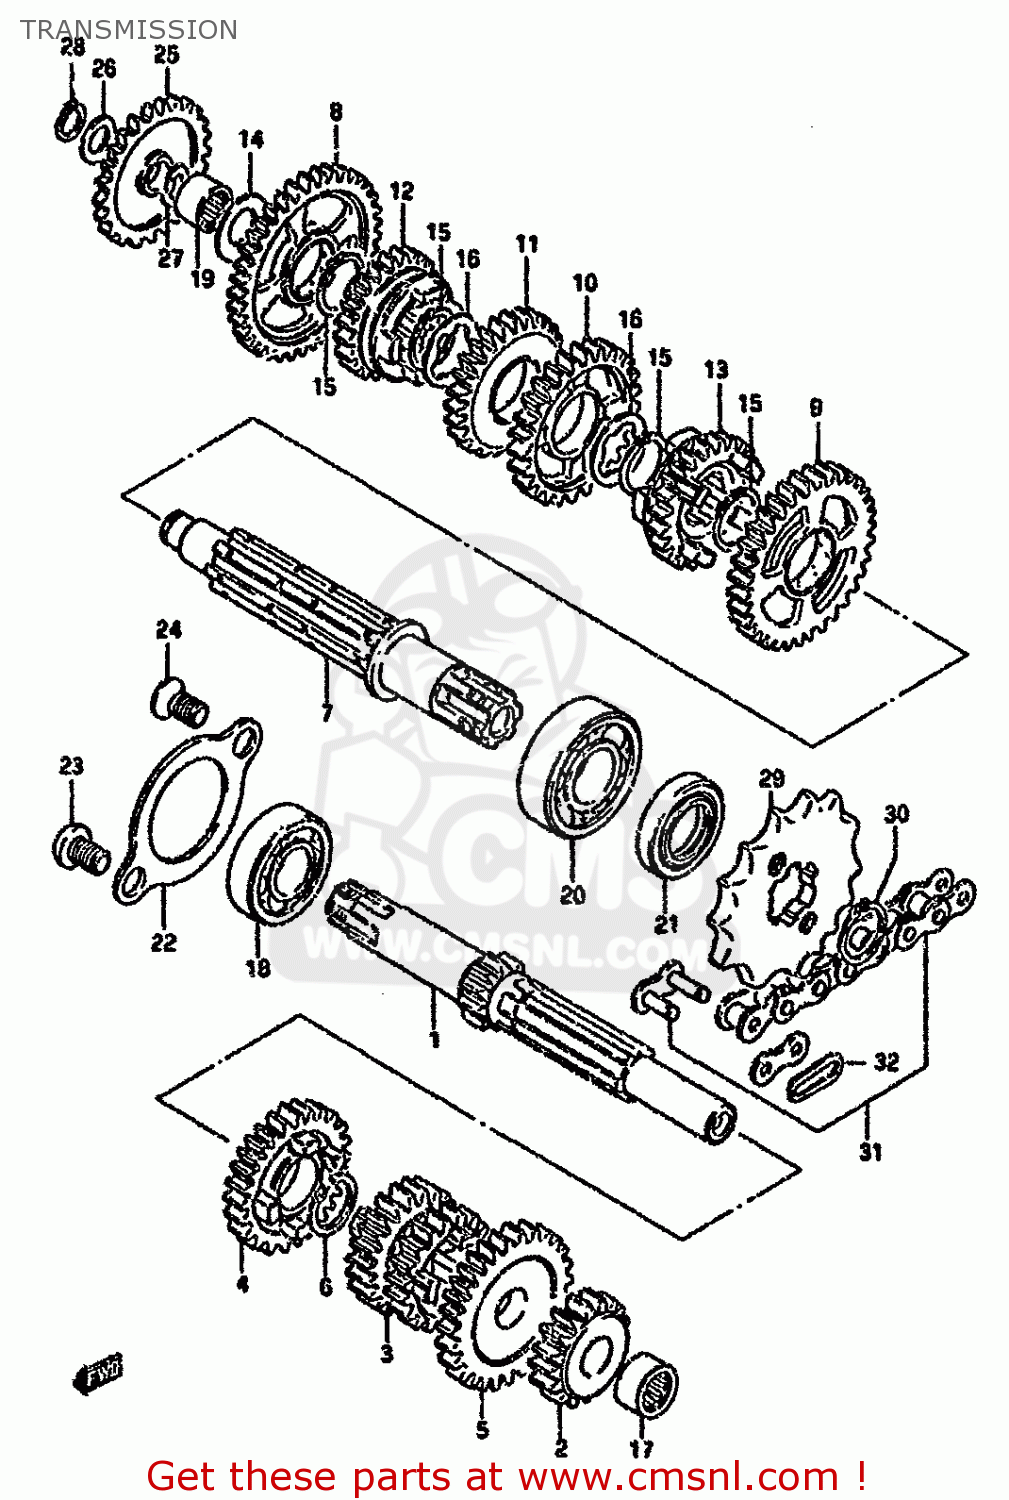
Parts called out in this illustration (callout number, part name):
1	SHAFT,COUNTER
2	GEAR,2ND DRIVE(NT:17)
3	GEAR, 3/4
4	GEAR, 5TH DRIVE
5	GEAR,6TH DRIVE(NT:26)
6	CIRCLIP
7	SHAFT,DRIVE
8	GEAR,1ST DRIVEN (NT:37)
9	GEAR, 2ND DRIVEN
10	GEAR, 3RD DRIVEN
11	GEAR,4TH DRIVEN(NT:28)
12	GEAR, 5TH DRIVEN
13	GEAR, 6TH DRIVEN
14	RING
15	CIRCLIP
16	WASHER,LOCK
17	ROLLER BEARING (13X19X1
18	BEARING(17X40X12)
19	BEARING(15X21X12)
20	BEARING(20X47X14)
21	OIL SEAL (20X35X5)
22	RETAINER,CNTR SHAFT BEARING
23	SCREW
24	SCREW
25	GEAR,KICK STARTER IDLER(NT:26)
26	THRUST WASHER
27	WASHER
28	CIRCLIP,12 MM
29	SPROCKET,ENGINE(NT:14)
30	CIRCLIP
31	CHAIN,DRIVE(DID428HG,134L)
32	JOINT,CHAIN
